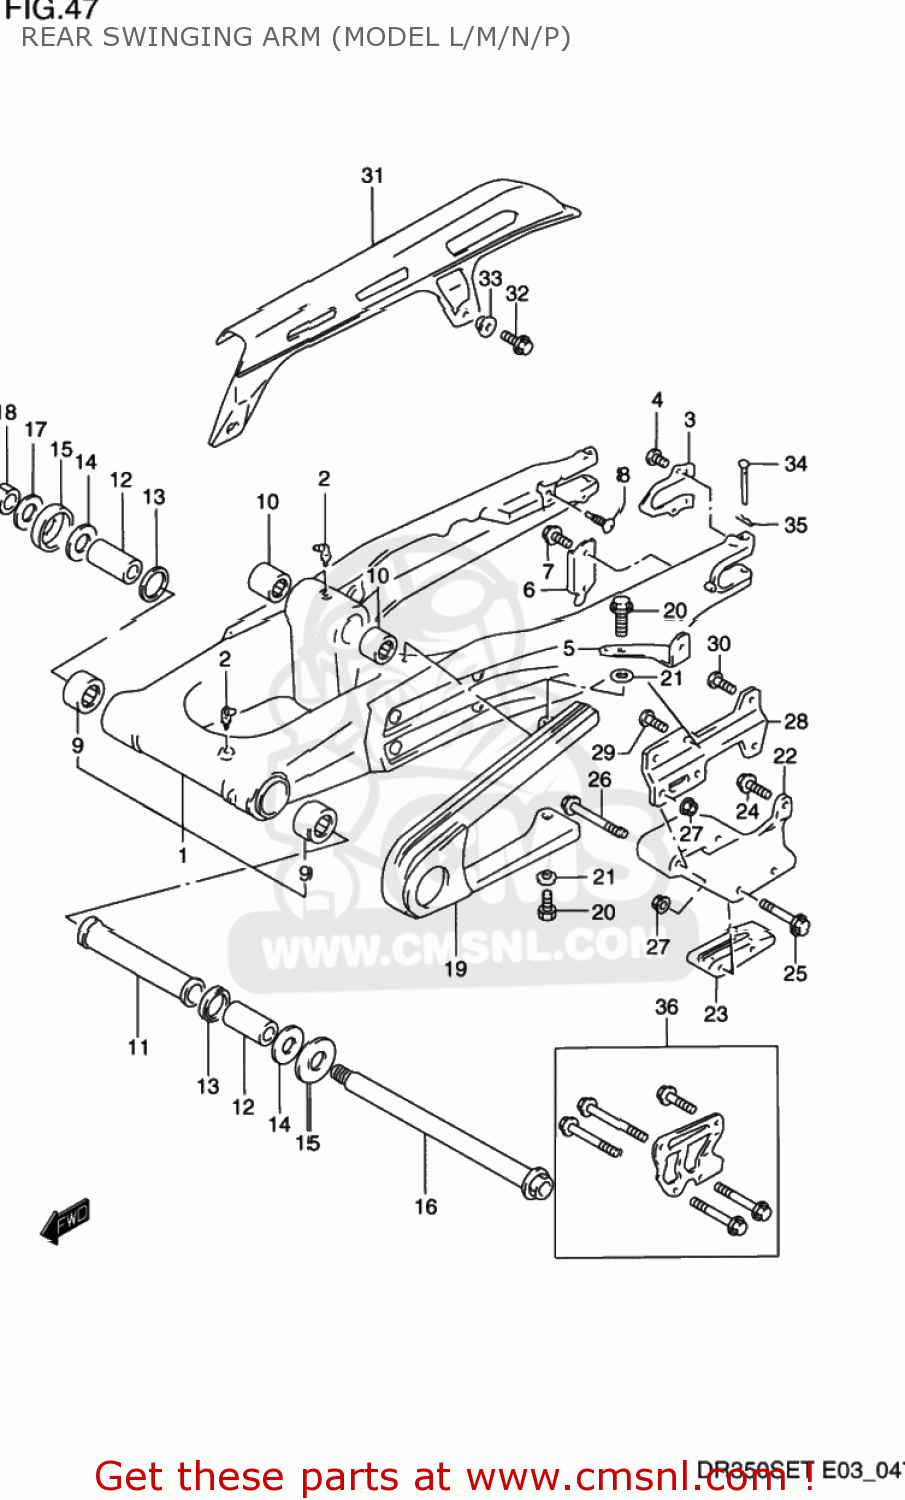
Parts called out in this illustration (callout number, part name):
1	SWING ARM ASSEMBLY,REAR
2	NIPPLE,GREASE
3	PLATE,SWING ARM RR
4	SCREW (5X8)
5	PLATE,CHAIN CASE FTG FR
6	PLATE,CHAIN CASE FTG RR
7	BOLT
8	SCREW (M10X21)
9	BEARING(22X29X30)
10	BEARING(20X27X23.5)
11	SPACER,SWING ARM PIVOT,CENTER
12	SPACER,SWGARM PIVOT BRG
13	SEAL,OIL(22X29X4)
14	WASHER
15	COVER,SWINGINGARM PIVOT
16	SHAFT,SWINGING ARM PIVOT
17	WASHER
18	NUT
19	BUFFER,CHAIN TOUCH DEFENSE
20	BOLT
21	WASHER
22	GUIDE,CHAIN
23	DEFENSE,CHAIN GUIDE
24	BOLT 6X25
25	BOLT,UNDER
26	BOLT
27	NUT
28	BRACKET,CHAIN GUIDE
29	SCREW
30	BOLT
31	CASE,CHAIN
32	BOLT
33	WASHER
34	PIN
35	CLIP
36	PLATE SET,CHAIN GUIDE
